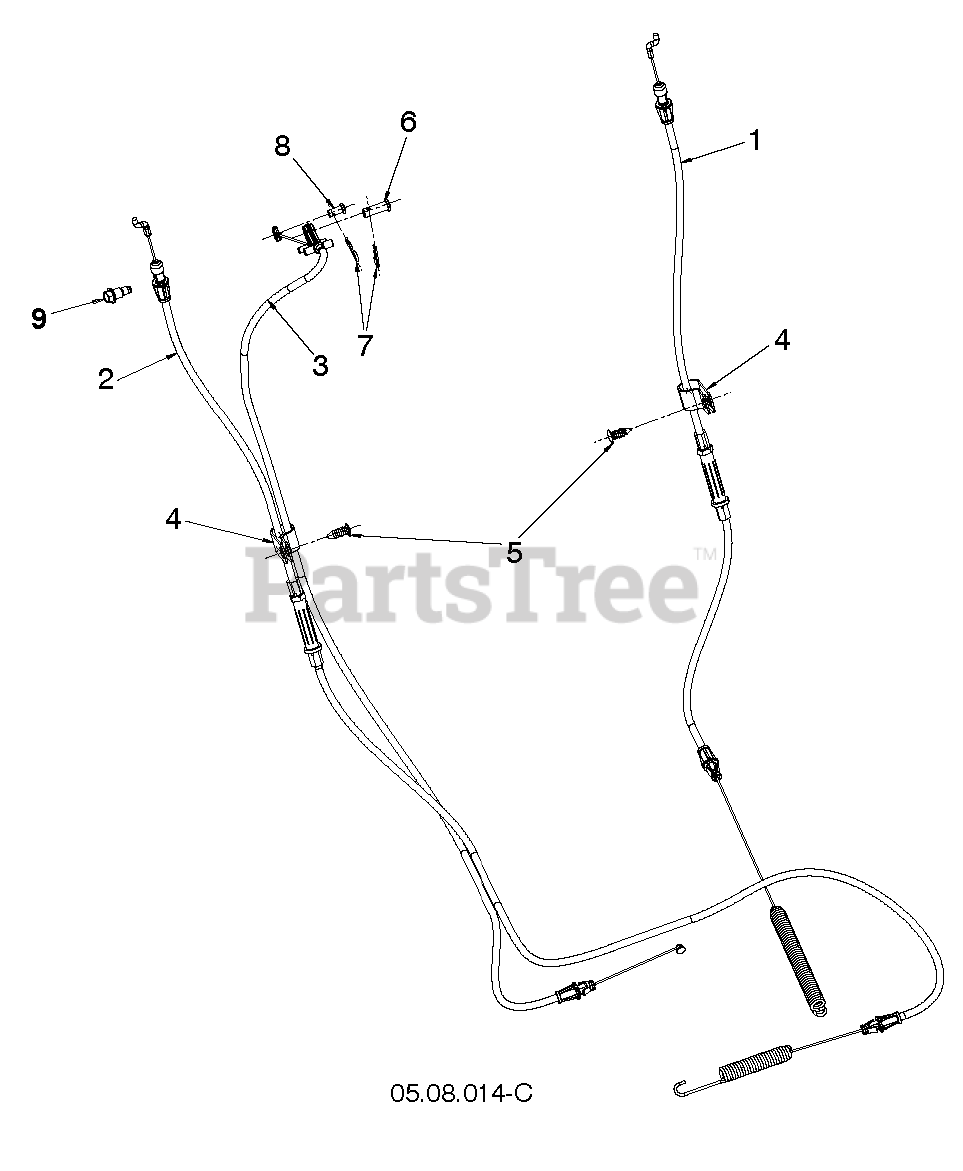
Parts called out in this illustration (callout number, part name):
1	CABLE.DRIVE CONTROL W/ADJ
1	CABLE.CONTROL.DRIVE.DSST.OPP
2	CABLE.CONTROL.AUGER
2	CABLE.CONTROL.AUGER.DSST.OPP.M
3	Cables
3	CABLE.CONTROL.SPEED.DSST.OPP
4	CLIP.CABLE.BLK
5	FASTENER.PUSH.O.250X0.783
6	PIN CLEVIS 5/16X.875
7	HAIRPIN.SOFT.ZINC.059X1.125
8	PIN CLEVIS .25 X .31
9	BOLT SHOULDER_1/4-20_TRILOB
